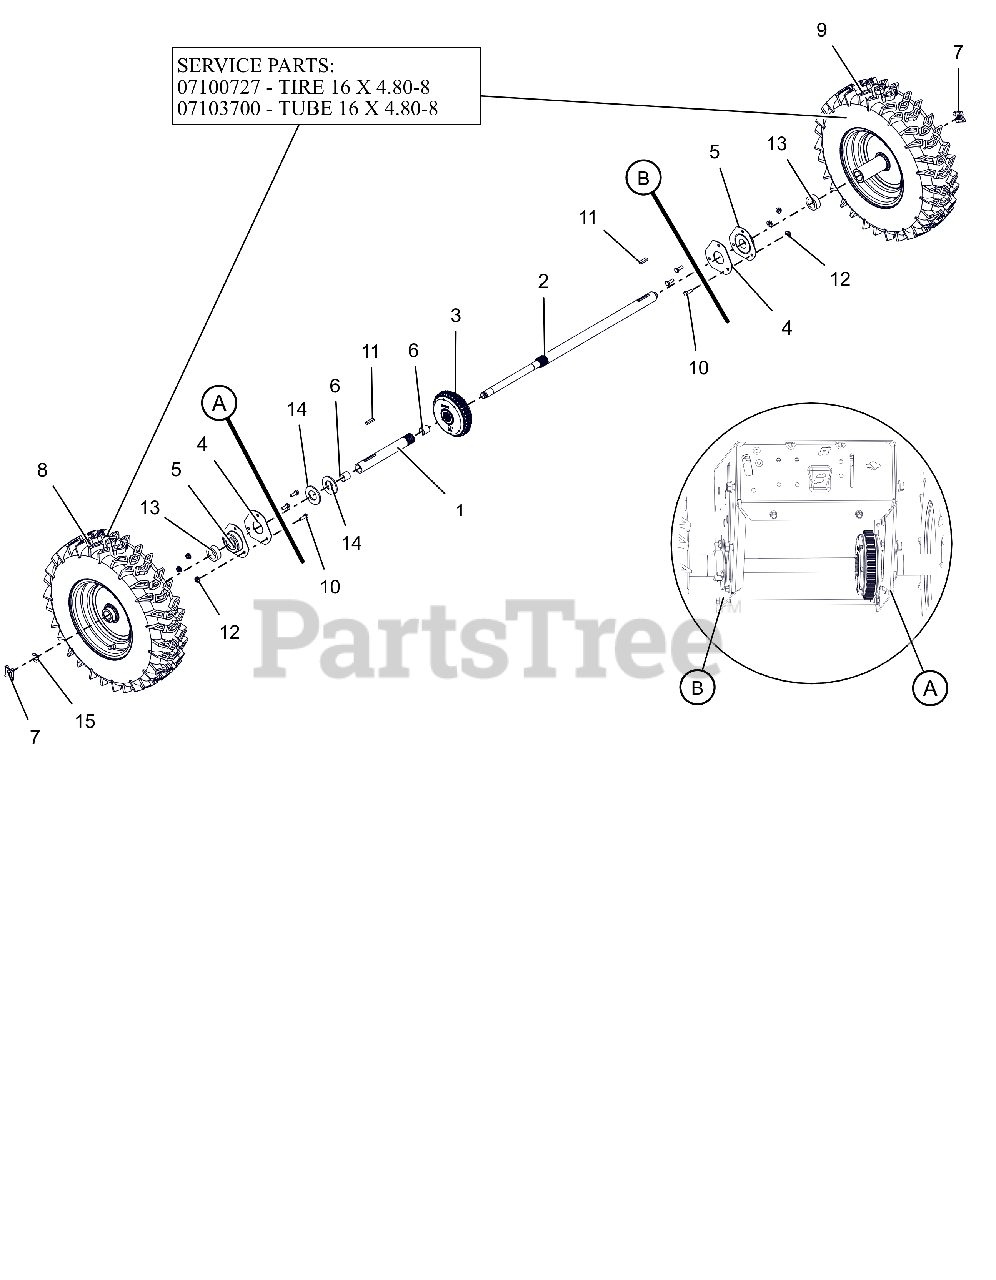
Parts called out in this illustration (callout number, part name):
1	AXLE, SHORT-AUTO W/BUSHINGS
2	AXLE, LONG-PRO AUTO DIFF
3	DIFFERENTIAL, AUTOMATIC
4	PLATE, BEARING SPACER
5	BRG-FLG 1.003/1.000 3 BOLT
6	BSHG-SLV .706X.764X.75 BRZ
7	CLIP, SNAP .625 DIA
8	TIRE/WHEEL,RH 16X4.8-8 DIFF T2
8	TIRE, 4.80-8 K478
8	TUBE
9	TIRE/WHEEL,LH 16X4.8-8 DIFF T2
10	@BLT-HEX .25-20X.75 GR5 YWZC
11	KEY-RECT .25X.188X1.00
12	@NUT-LK-CTR-FLG .25-20 YWZC
13	SPACER, PRO AXLE BEARING
14	WSHR-FL-STL- 1.062X2.0X.134 YZ
15	RG-RTNG-EXT .625X.042
